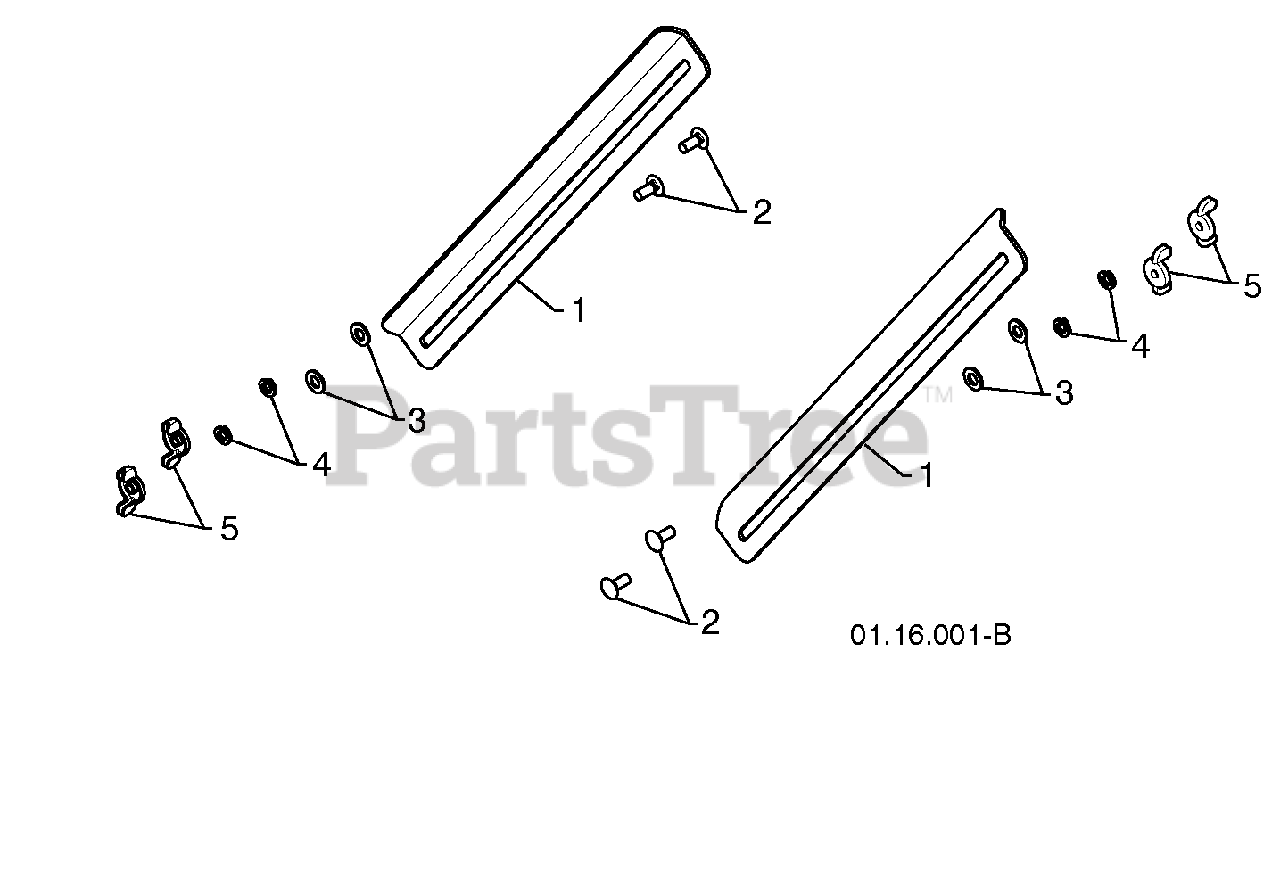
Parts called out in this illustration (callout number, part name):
1	DRIFT CUTTER BAR
2	CARRIAGE BOLT 5/16-18 X .750
3	PLASTIC WASHER
4	LOCKWASHER 5/16
5	NUT 5/16-18
